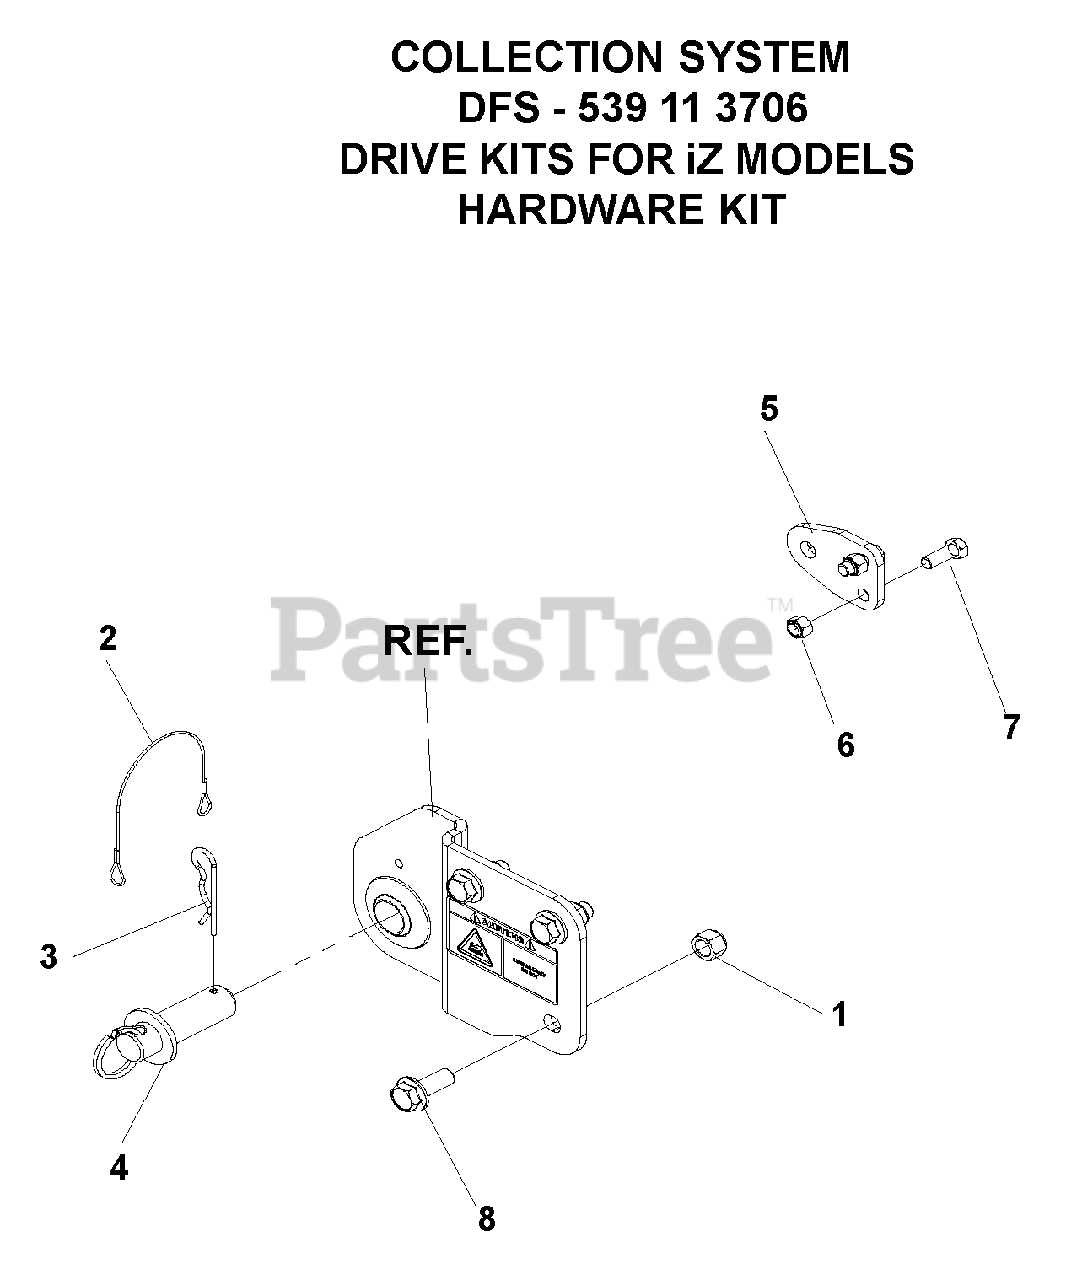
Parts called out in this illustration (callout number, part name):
1	NUT, 1/2-13, NYLOC
5	SUPPORT BRACKET
6	NUT, 3/8-16, NYLOC
7	HCS, 3/8-16 X 1, GR5
8	BOLT, 1/2-13 X 1 1/4, WHIZLK
539113706	Drive Kits
